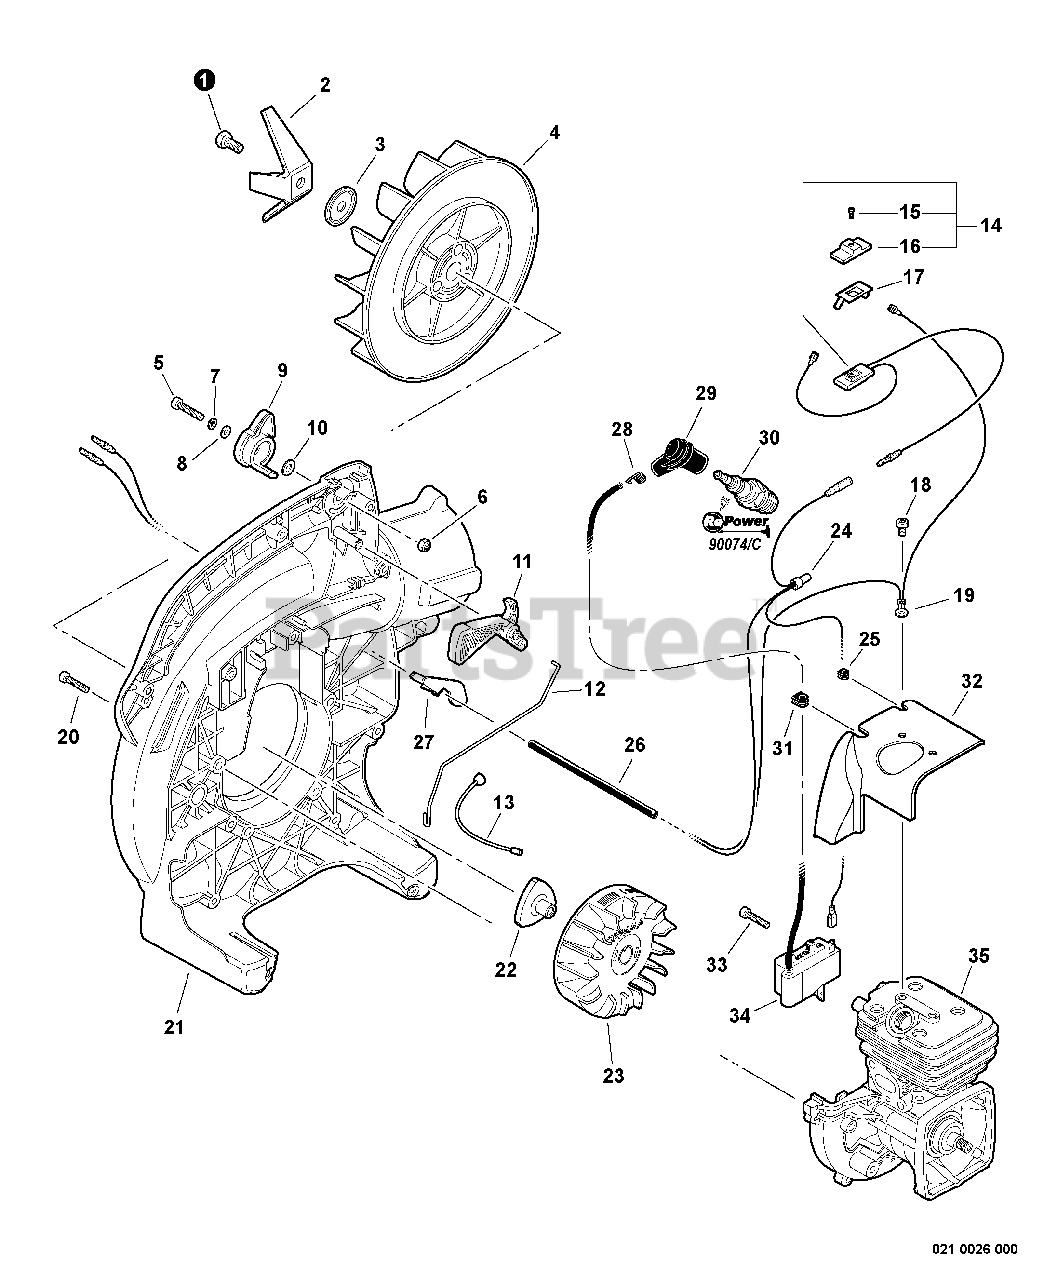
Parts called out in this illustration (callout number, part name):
1	SCREW - 8X15
2	CUTTER, SHREDDER
3	WASHER - CUP
5	SCREW - 5X25
6	LOCKNUT - 5
7	LOCKWASHER - 5
8	WASHER - 5
9	LEVER, THROTTLE
10	WASHER - 5
11	TRIGGER, THROTTLE
12	ROD, THROTTLE
13	CABLE, THROTTLE
14	IGNITION SWITCH ASSY
15	SCREW - 3X10
16	KNOB, SWITCH - ORANGE
17	TERMINAL - GROUND
18	SCREW - 5X8
19	LEAD - GROUND
20	SCREW - 4X20
21	COVER, FAN - RIGHT
22	HUB, FAN
23	FLYWHEEL
24	LEAD - IGNITION
26	TUBE, INSULATOR
28	TERMINAL, SPARK PLUG CAP
29	CAP, SPARK PLUG
30	SPARK PLUG -- BPM-8Y
30	SPARK PLUG -- BPMR-8Y
32	SHIELD, CYLINDER
33	SCREW - 4X20
34	COIL, IGNITION
35	SHORT BLOCK -- SB1104
36	RePower TUNE-UP KIT
